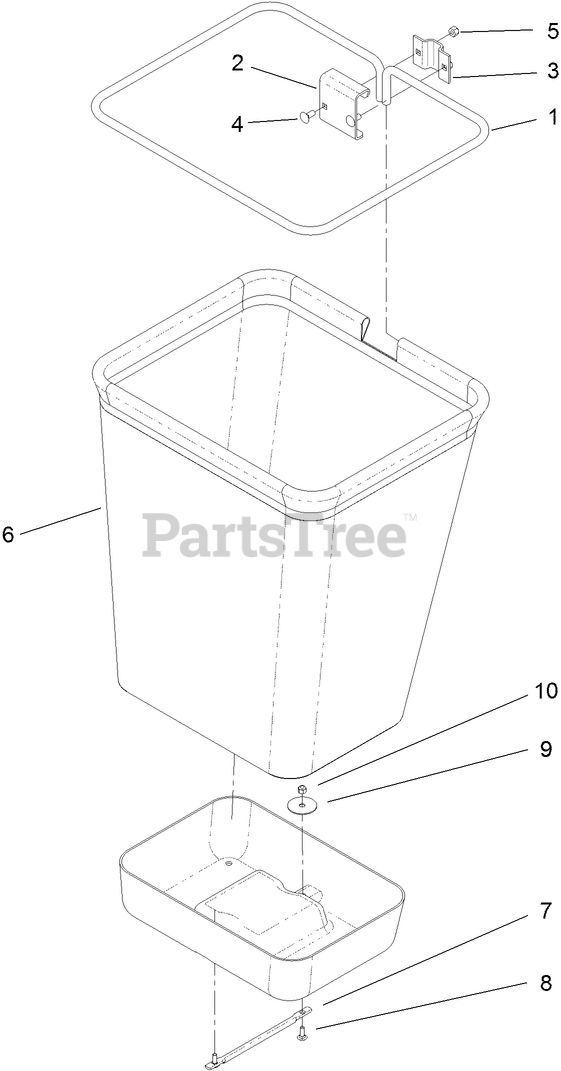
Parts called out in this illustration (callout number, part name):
1	FRAME-BAG
2	HANGER-BAG
4	BOLT-CARR
5	NUT-LOCK, NI
6	BAG ASM
7	HANDLE-BAG
8	BOLT-CARR
9	WASHER
10	NUT-LOCK, NI
